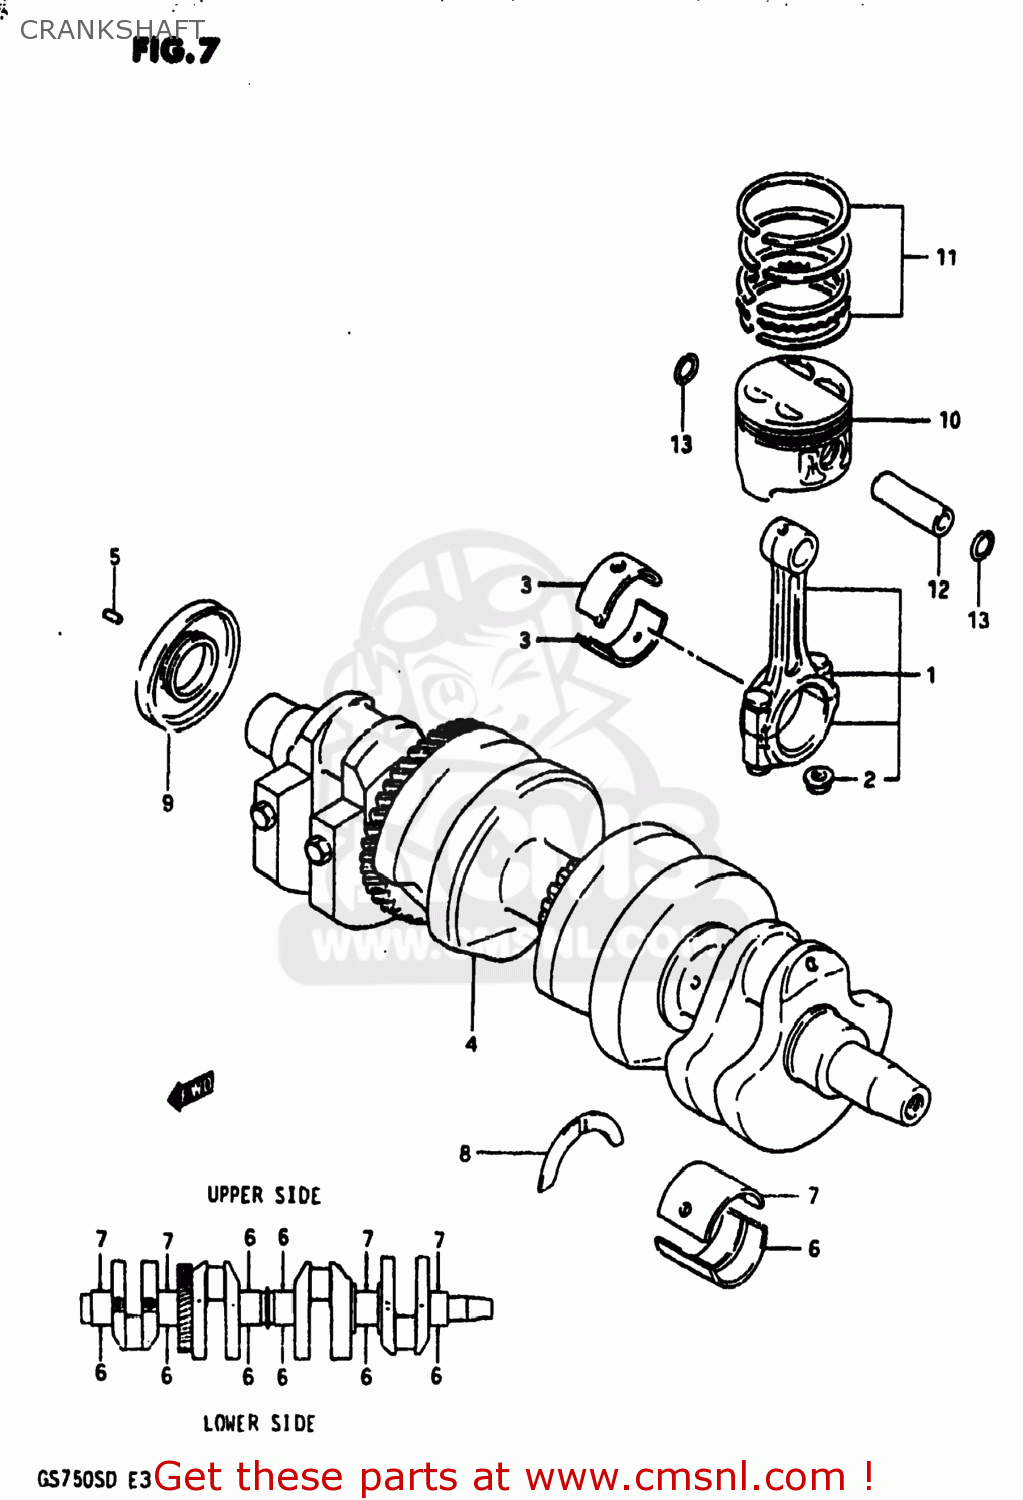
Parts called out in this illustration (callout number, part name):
1	ROD ASSEMBLY,CONNECTING
2	NUT
3	BEARING,CRANK PIN
4	CRANKSHAFT
5	PIN
6	METAL CRANKSHAFT
7	METAL CRANKSHAFT
8	PLATE,CRANK THRUST
9	OIL SEAL
10	PISTON
11	RING SET,PISTON
12	PIN,PISTON (18MM)
13	CIRCLIP
